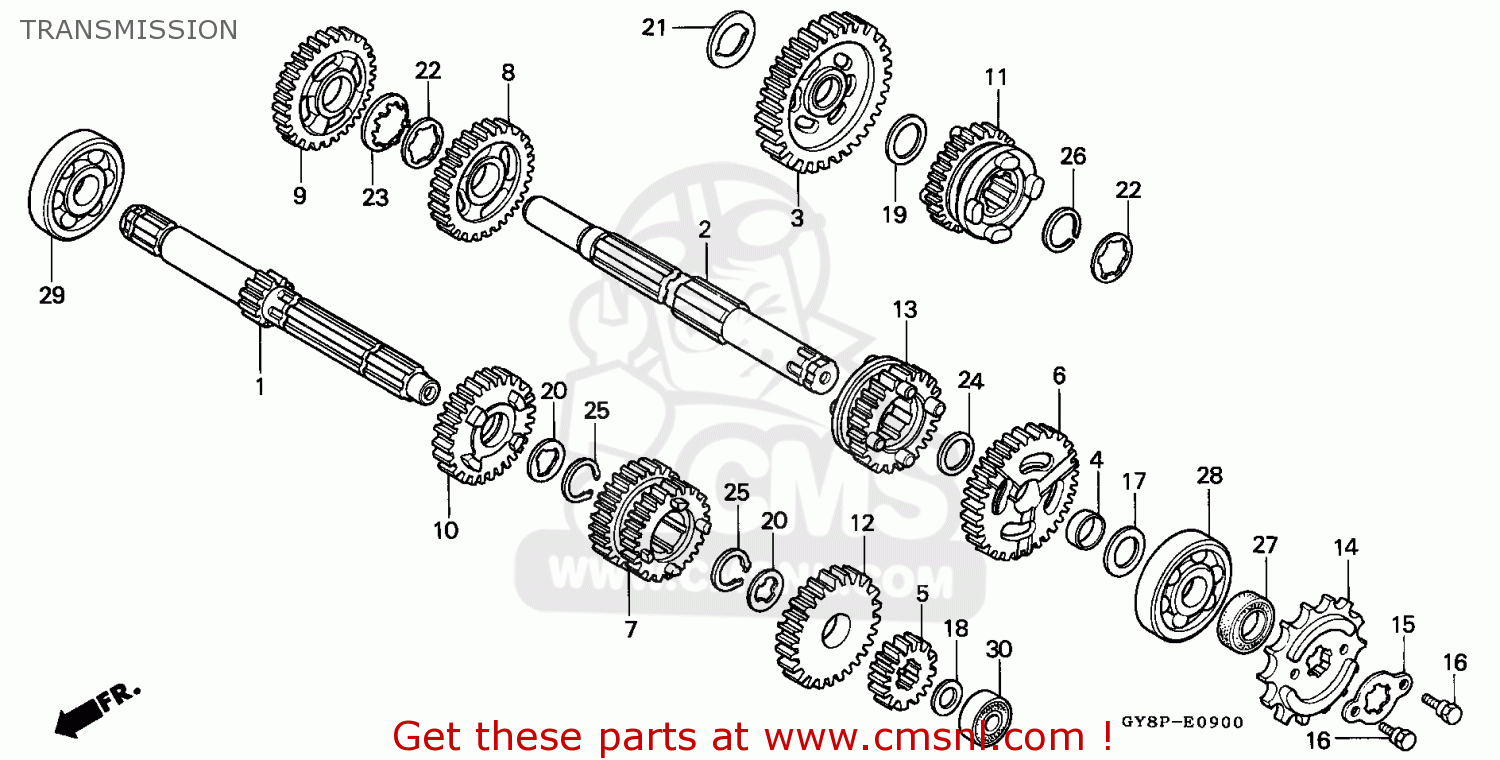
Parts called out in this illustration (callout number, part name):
1	SHAFT,MAIN TRANSM
2	SHAFT,COUNTER TRA
3	GEAR COMP.,COUNTE
4	BUSH,17MM
5	GEAR,MAINSHAFT SE
6	GEAR,COUNTERSHAFT
7	GEAR,MAINSHAFT TH
8	GEAR,COUNTERSHAFT
9	GEAR,COUNTERSHAFT
10	GEAR,MAINSHAFT FI
11	GEAR,COUNTERSHAFT
12	GEAR,MAINSHAFT SI
13	GEAR,COUNTERSHAFT
14	SPROCKET,DRIVE
15	PLATE,FIXING
16	BOLT, SPROCKET
17	WASHER,17.2MM
18	WASH,THRUST 12MM
19	WASHER,THR.16.5MM
20	WASHER,17MM
21	WASH,THRUST 15MM
22	WASH A,SPLINE
23	WASHER,LOCK 19MM
24	WASH,THRUST,17MM
25	CIRCLIP, 17M/M
26	CIRCRLIP,19MM
27	OIL SEAL,17X28X7
28	B/BRG RAD N/COM
29	B/BRG RAD N/COM
30	B/BRG RAD N/COM
